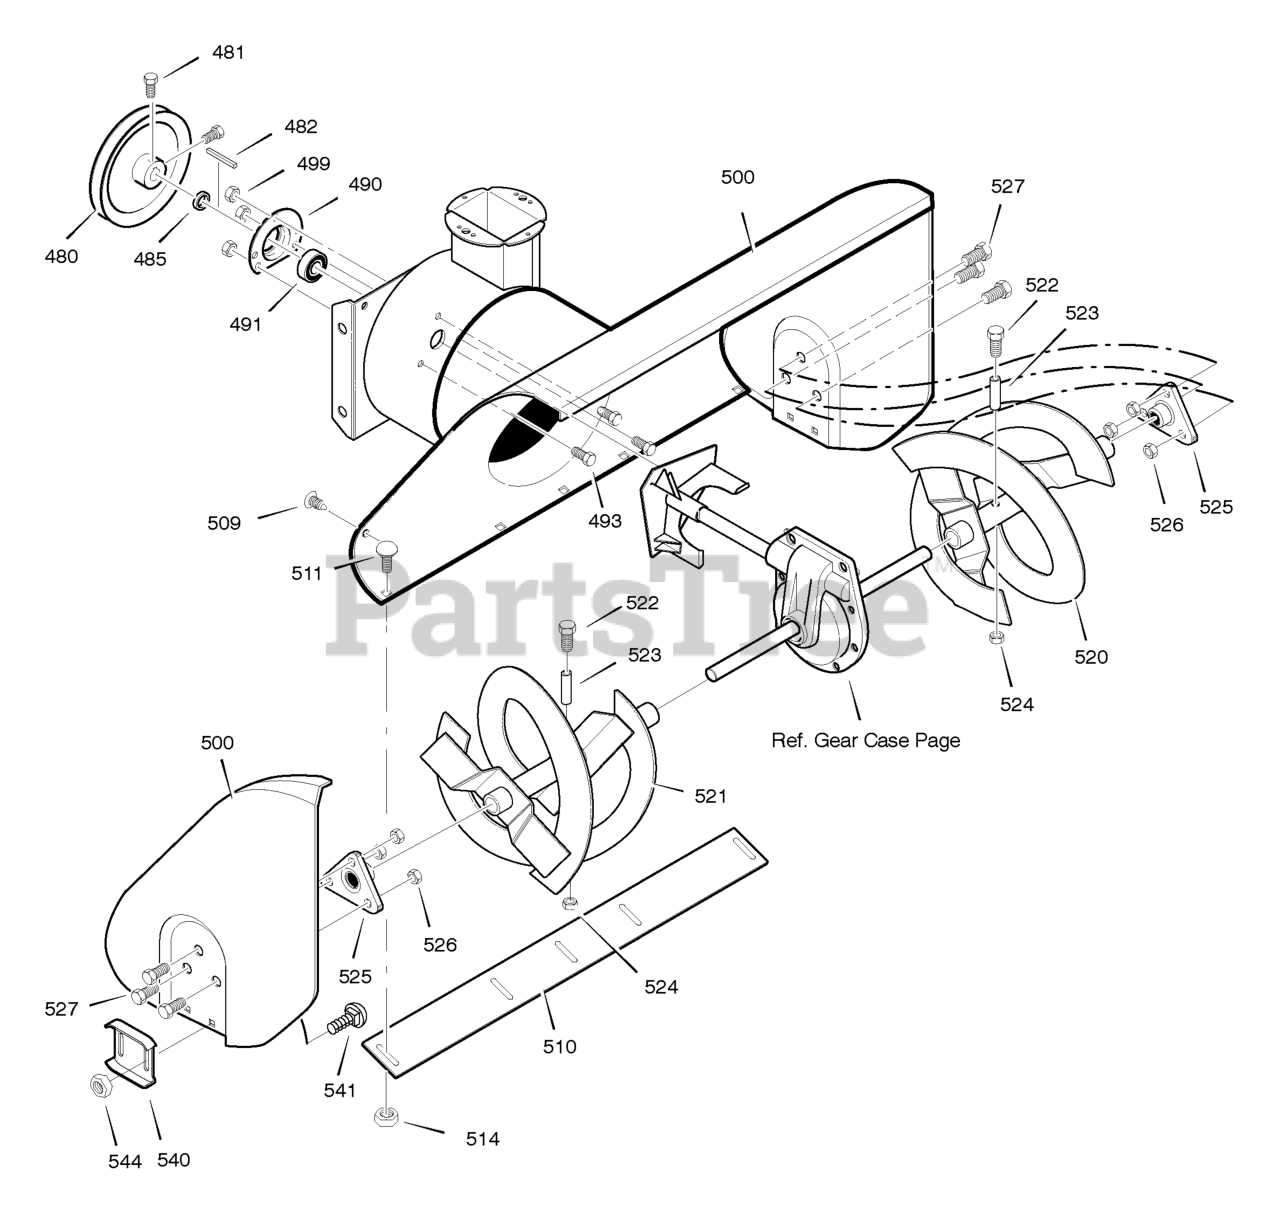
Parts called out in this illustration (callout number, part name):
480	PULLEY, 4L 8.4 X .67 HYBRID
481	SCREW, 5/16-18 x 0.62
482	KEY, SQUARE 3/16 X 3/4
485	SPACER, FRICTION PULLEY
490	RETAINER, BALL BRNG
491	BEARING, BALL
493	BOLT, HEX 5/16-18X .50
499	NUT, 5/16-18 HEXWDFLLK
500	HOUSING, ASSY
509	PLUG, CHRISTMAS TREE
510	BLADE, SCRAPER
511	BOLT, 5/16-18X.75
514	NUT, 5/16-18
520	AUGER, ASSY, LH
521	AUGER, ASSY, RH
522	SCREW, 1/4-20X1.75
523	SPACER, SLEEVE
524	NUT, 1/4-20
525	BEARING,FLANGE
526	NUT, 5/16-18
527	SCREW, 5/16-18 x 0.75
540	SKID, HEIGHT ADJUST
541	BOLT, 5/16-18 X .75
544	NUT, 5/16-18
